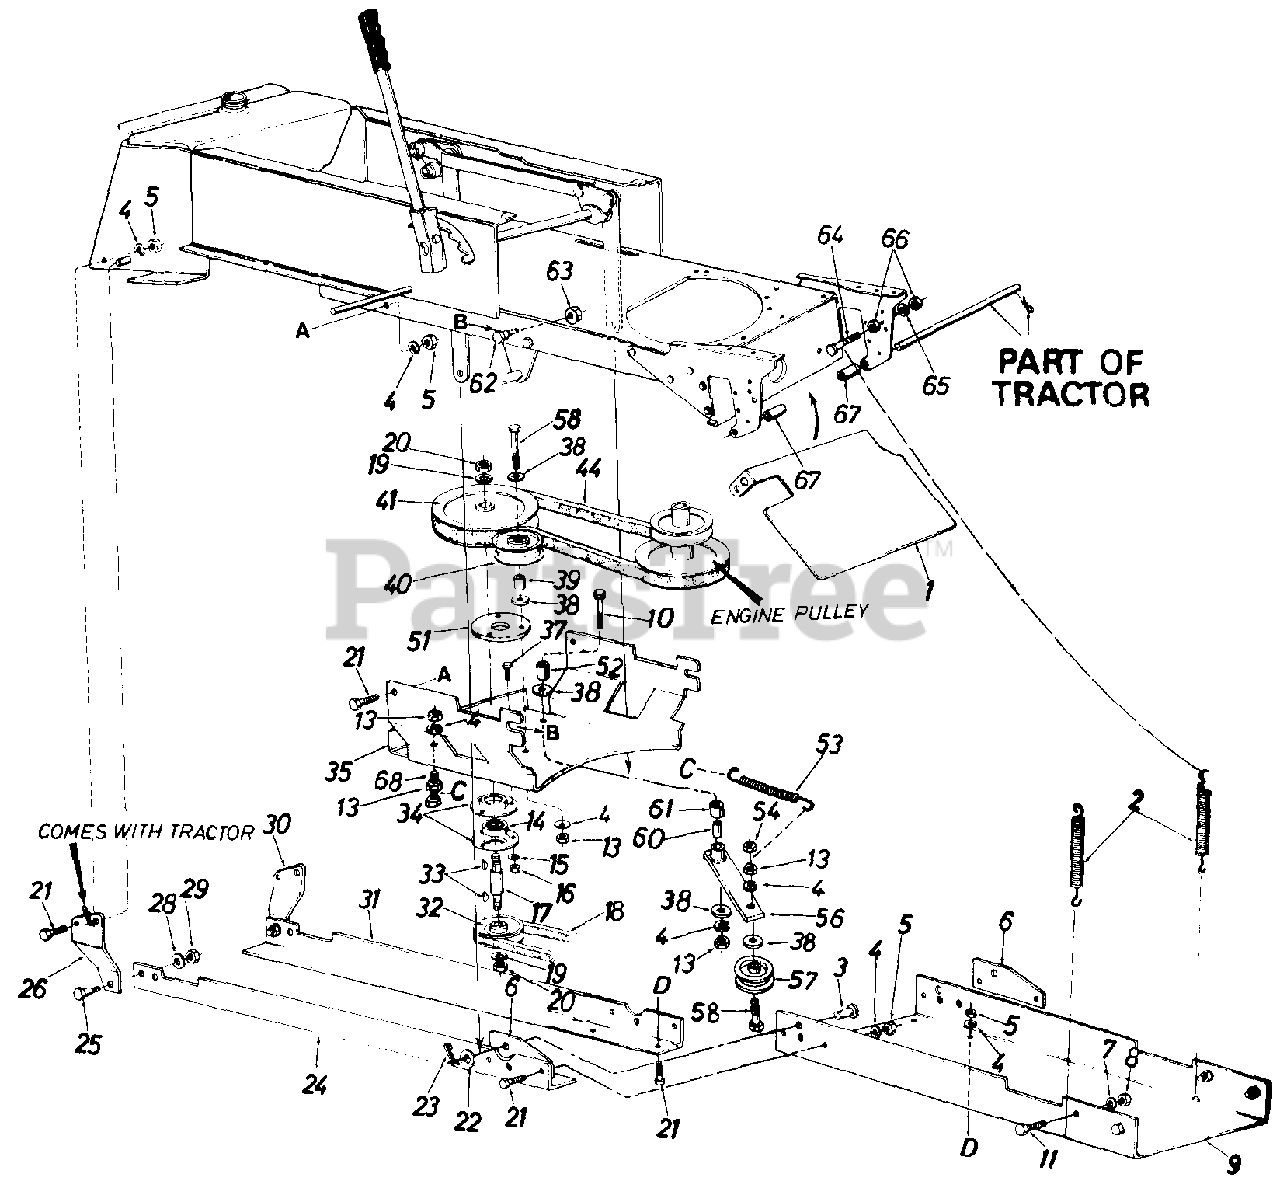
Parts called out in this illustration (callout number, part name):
3	Clevis Pin
4	L.-Wash. 3/8" I.D.
5	Hex L.-Nut 3/8-24 Thd.
6	Attaching Plate
7	L.-Wash. 1/2" I.D.
8	Hex L-Nut 1/2-20 Thd.
11	Hex Bolt 1/2-20 x 1.25" Lg.
13	Hex Jam Nut 3/8-16 Thd.
14	Ball Bearing
15	L.-Wash. 5/18" I.D.
16	Hex Nut 5/16-18 Thd.
17	Spindle
19	L-Wash. 5/8" I.D.
20	Hex Jam Nut 5/8-11 Thd.
21	Hex Bolt 3/8-24 x 1.00" lg.
22	Flat Washer
23	Internal Cotter Pin
24	Radar Support Angle - R.H.
25	Shld. Bolt .623" Die.
29	Hex Nut 7/16-14 Thd.
33	#6 Hi-Pro Key 3/16 x 5/8" Dia.
34	Bearing Housing
35	Supporting Bracket
37	Hex Sems Bolt 5/16-18 x 1"
38	Fl.-Wash..38" I.D. x 1" O.D.
39	Spacer .38" I.D. x .62" O.D.
40	Fl.-Idler Pulley
41	Upper Drive Pulley
44	"V"-Belt
53	Extension Spring 4.75" Lg.
54	Hex Cent. L.-Nut 3/8-16 Thd.
56	Idler Arm Ass'y.
57	Idler Pulley
58	Hex Bolt 3/8-18 x 2.25" Lg.
60	Spacer .377" I.D. x .83" Lg.
61	Spacer .38" I.D. x .565" Lg.
62	Shoulder Bolt .498 Dia.
63	Hex Cent. L-Nut 3/8-16 Thd.
64	Hex Bolt 1/4-28 x 1.50" Lg.
65	L-Wash. 1/4" I.D.
66	Hex Nut 1/4-28 Thd.
67	Spacer .63" I.D. x 1.75" Lg.
68	Hex Bolt 3/8-16 x 2" Lg.
